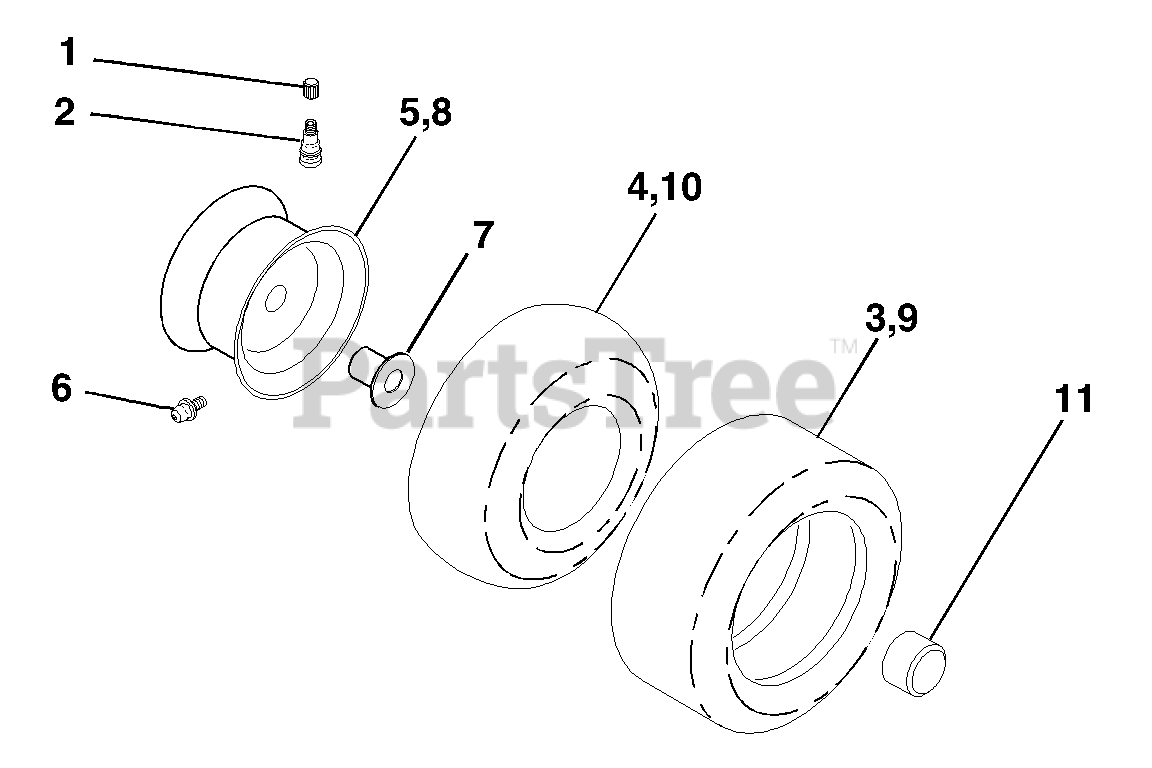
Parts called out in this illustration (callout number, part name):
1	Cap Valve Tire
2	Stem Valve
3	Tire F Ts 15 X 6 0 - 6 Service
4	Tube Front (Service Item Only)
5	Rim Asm 6" front Service
6	Fitting Grease (Front Wheel Only)
7	Bearing Flange (Front Wheel Only)
8	Rim Asm 8" rear Service
9	Tire R Ts 20x10-8 C Service
10	Tube Rear (Service Item Only)
11	Cap Axle 1 50 X 1 00
